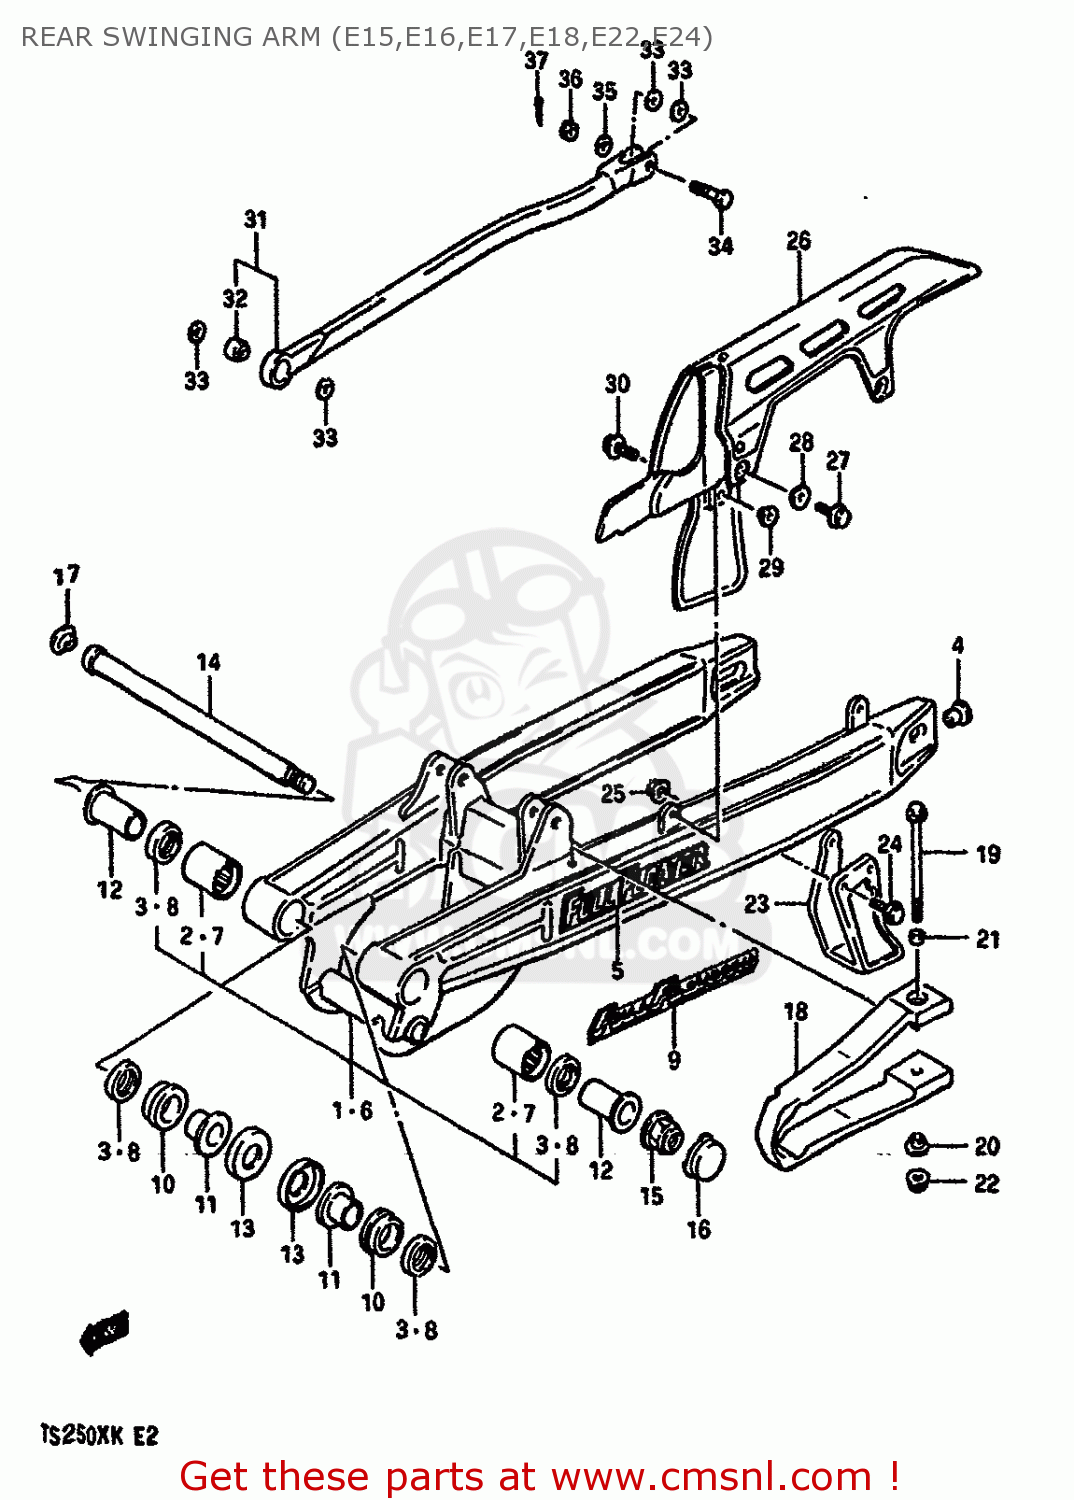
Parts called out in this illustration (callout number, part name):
1	SWINGING ARM ASSY,REAR
2	BEARING(20X27X20)
3	OIL SEAL
4	SUPPORT
5	EMBLEM
6	SWINGING ARM ASSY,REAR
7	BEARING(20X27X20)
8	OIL SEAL
9	EMBLEM,SWING ARM
10	BUSHING,REAR SWING ARM PIVOT
11	SPACER,RR SWGARM PIVOT INNER
12	SPACER,RR SWGARM PIVOT
13	COVER,RR SWGARM DUST SEAL
14	SHAFT
15	NUT
16	CAP,PIVOT
17	CAP,SHAFT
18	BUFFER
19	BOLT
20	WASHER
21	SPACER (5.5X8X4)
22	NUT
23	GUIDE,CHAIN
24	BOLT
25	NUT
26	CASE,CHAIN
27	BOLT
28	WASHER
29	WASHER
30	BOLT
31	TORQUE LINK SET
32	BEARING
33	34
34	BOLT 8X29.5
35	WASHER
36	NUT 8MM
37	PIN 20X20
